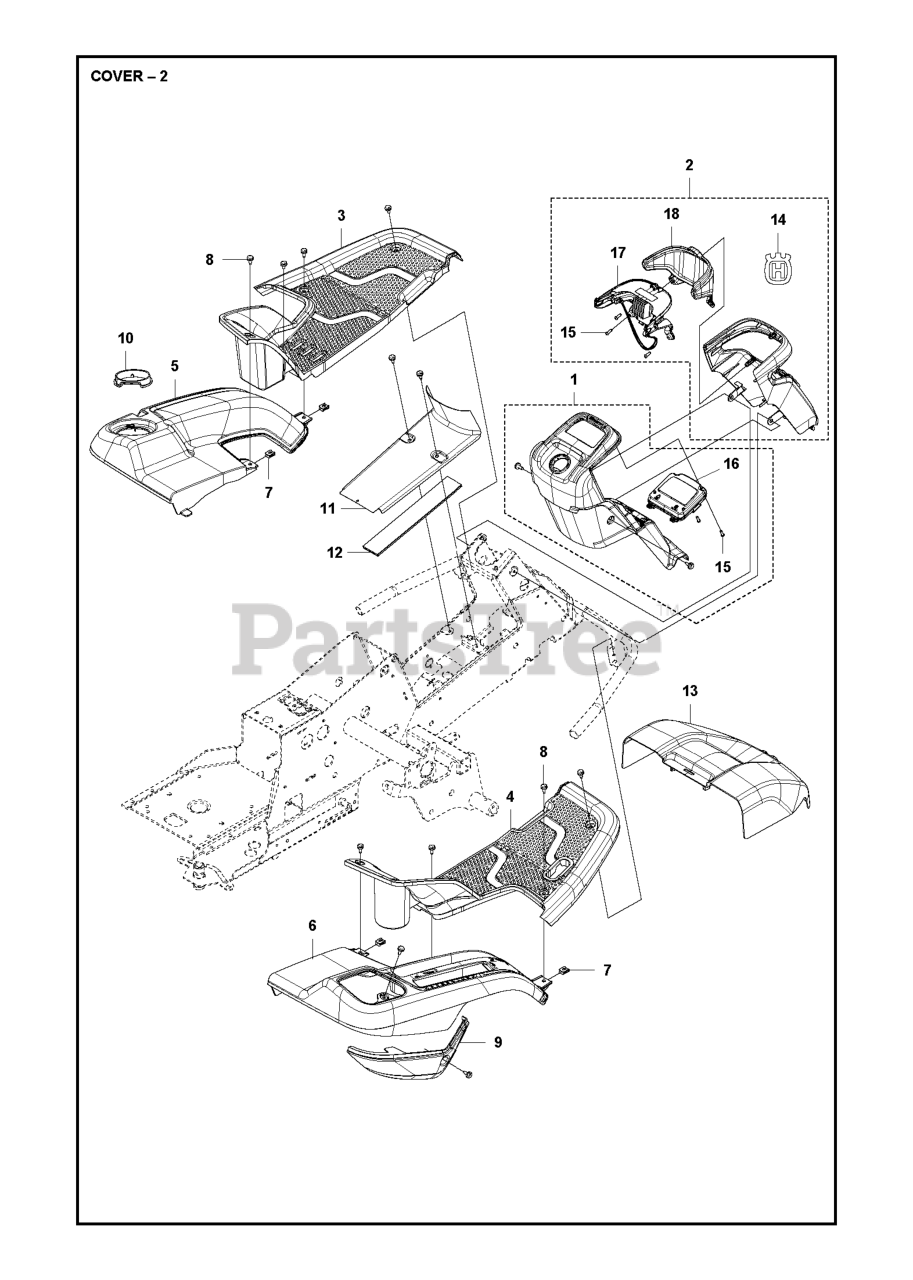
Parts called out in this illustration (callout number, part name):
3	FOOT PLATE
4	FOOT PLATE
9	CONTROL COVER
10	LOCKING NUT
12	MAT COVER FRAME
13	UNIT COVER
15	SCREW ITXPANT T50X16 ZN/FE (A
